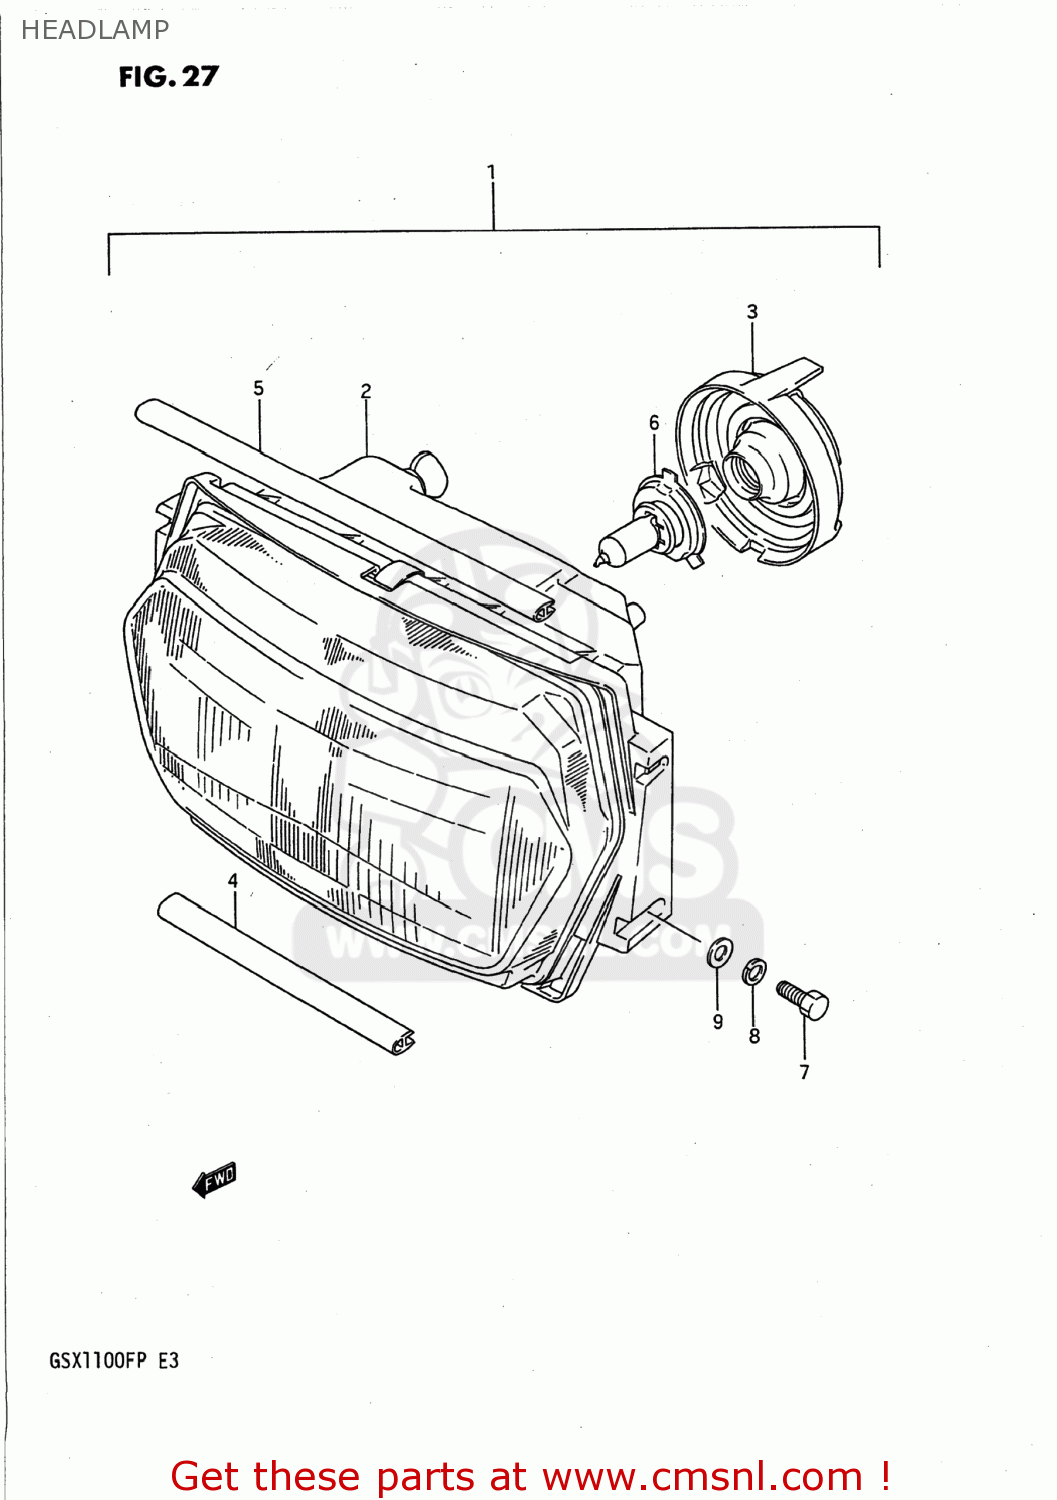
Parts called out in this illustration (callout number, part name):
1	HEADLAMP ASSEMBLY
2	UNIT
3	COVER,SOCKET
4	GASKET,HEADLAMP,LOWER (NAS)
5	GASKET,HEADLAMP,UPPER (NAS)
6	BULB(12V60/55W,H4)
7	BOLT
8	WASHER,LOCK
9	WASHER, LOWER
